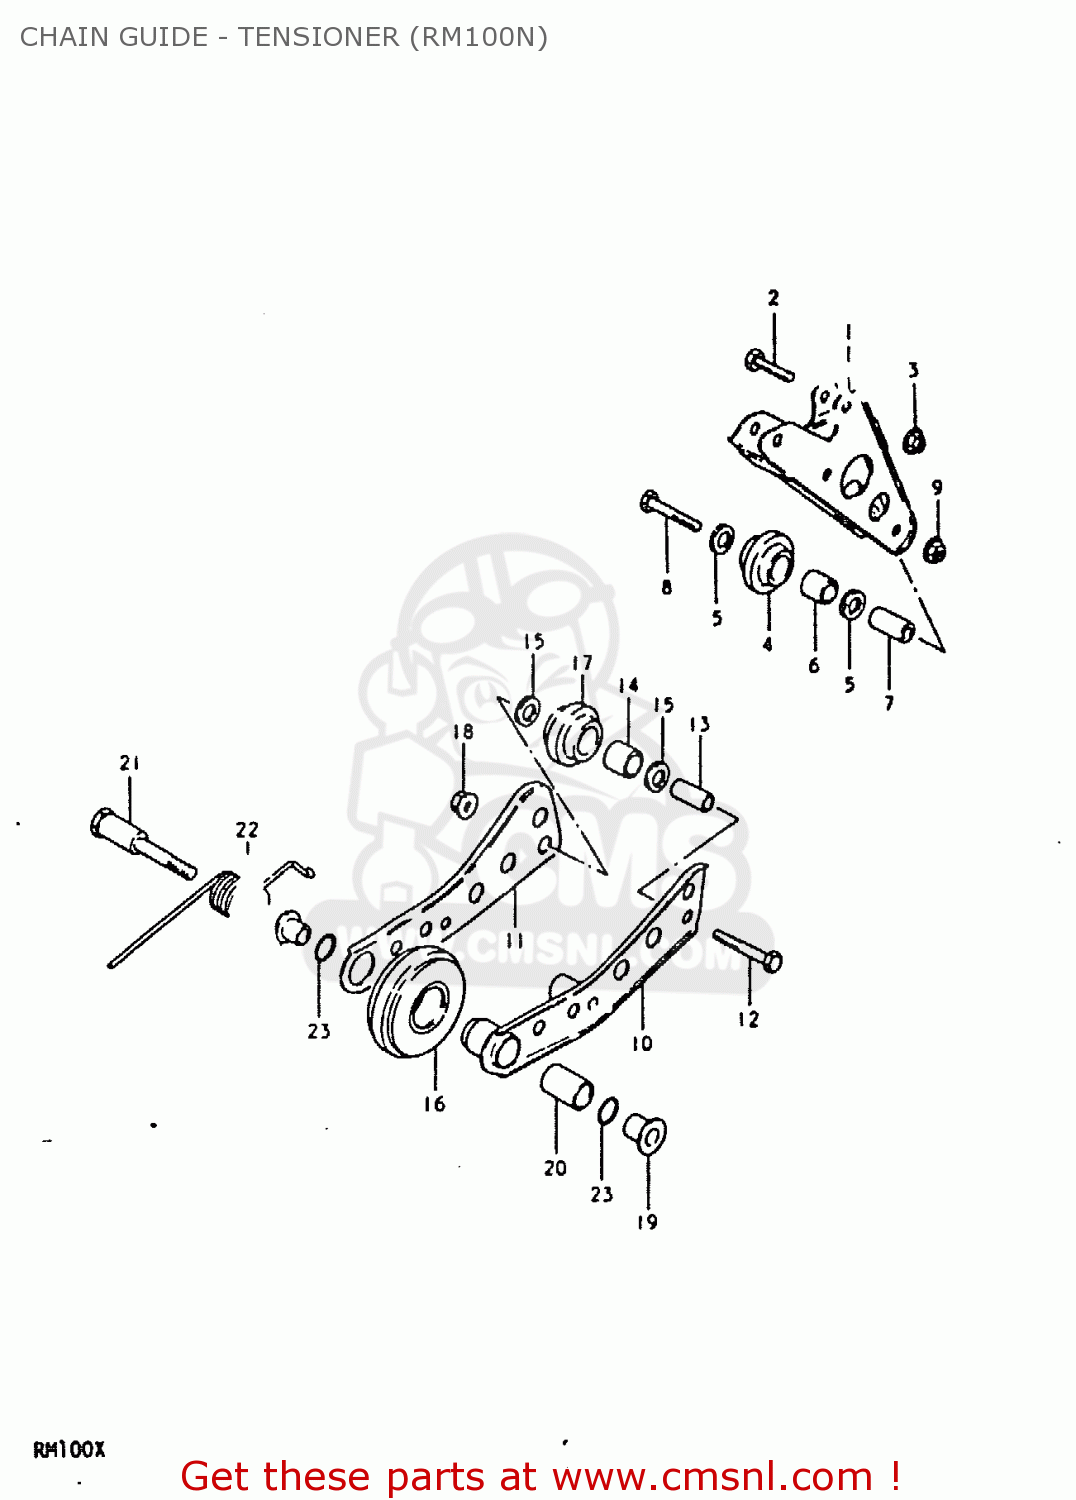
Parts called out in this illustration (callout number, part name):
1	GUIDE,DRIVE CHAIN
2	BOLT
3	NUT 6MM
4	ROLLER,CHAIN TENSIONER LWR
5	SEAL,OIL(10X14.4X3.5)
6	SPACER,CHAIN GUIDE
7	SPACER(6.2X10X22.5)
8	BOLT 6X35
9	NUT
10	TENSIONER,CHAIN
11	PLATE,CHAIN TENSIONER
12	BOLT 6X35
13	SPACER(6.2X10X22.5)
14	SPACER,CHAIN GUIDE
15	SEAL,OIL(10X14.4X3.5)
16	ROLLER,CHAIN GUIDE
17	ROLLER,CHAIN TENSIONER LWR
18	NUT
19	SPACER,CHAIN TENSIONER
20	BUSHING,CHAIN TENSIONER
21	BOLT
22	SPRING
23	O RING(D:1.3,ID:9.6)
